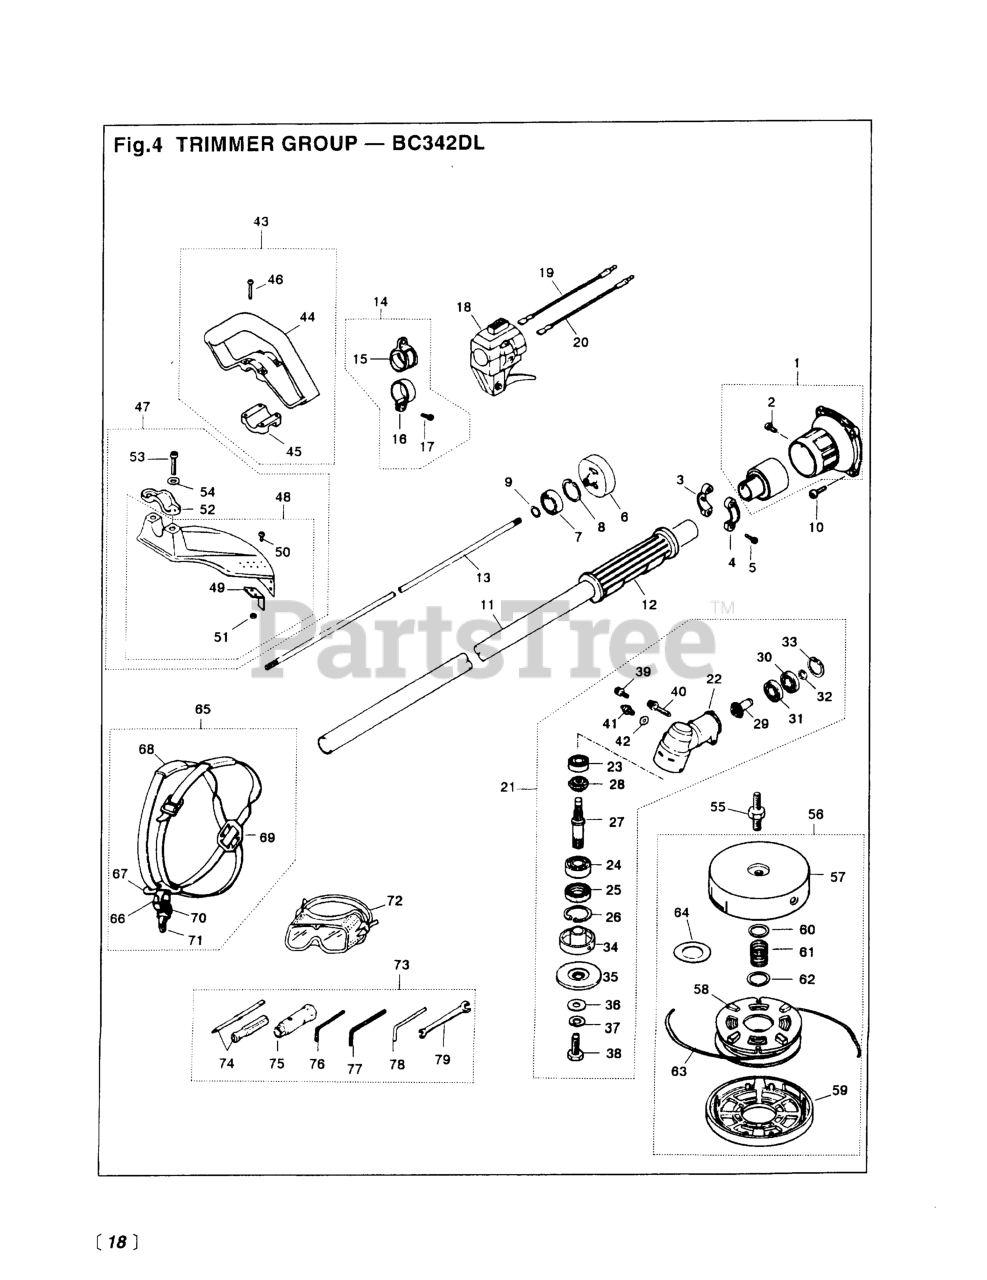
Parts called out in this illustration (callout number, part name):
1	HOUSING ASSY (RPLS-11100)
2	SCREW, M6 x 10
3	CLAMP, RIGHT (RPLS -11130)
4	CLAMP, LEFT (RPLS-11140)
5	BOLT
6	DRUM, CLUTCH
7	BEARING
8	RING, SNAP, M35 X 1.5
9	RING, SNAP, M15 X 1.0
10	BOLT, M6 x 20
13	SHAFT, SPLINE
14	HANGER ASSY. (NLA)
15	HANGER
16	CLAMP
17	SCREW, M5 x 25
19	CORD-A, BLACK
20	CORD-B, RED
21	GEARCASE (RPLS-13005)
22	GEARCASE (RPLS -13113)
23	BEARING (RPLS T3403-13510)
25	SEAL, OIL
26	RING, SNAP, M32 x 1.2
27	SHAFT, GEAR
28	GEAR, BEVEL
31	BEARING (RPLS T3403-13510)
32	RING, SNAP
33	RING, SNAP, M26 X 1.2
34	HOLDER (A)
35	HOLDER (B)
36	WASHER, M8 x 2.3 (RPLS -20823)
37	WASHER (RPLS 3180-13270)
38	BOLT, LH
39	BOLT, M5 X 10
40	BOLT, M6 x 1.35
41	FITTING, GREASE
42	WASHER, M6 X .8
43	HANDLE ASSEMBLY
44	HANDLE
45	CLAMP
46	SCREW, M5 x 35
47	GUARD ASSY (RPLS -24001)
48	GUARD COMP.
49	BLADE
50	SCREW, M5 x 12
51	NUT
52	CLAMP
53	BOLT, M6 x 1.30
54	WASHER, M6 X 15
55	ARBOR, 8MM
56	6
59	COVER
60	PLATE, LARGE
62	PLATE, SMALL
63	CORD
64	SPACER
65	HARNESS ASSY (USE 6565-17200)
68	PROTECTOR
71	HOOK COMP (RPLS -96414)
73	TOOL SET
74	SCREWDRIVER
76	WRENCH (TOOL)
77	WRENCH (TOOL)
78	BAR
79	SPANNER, 8 X 10 (RPLS 2540- )
